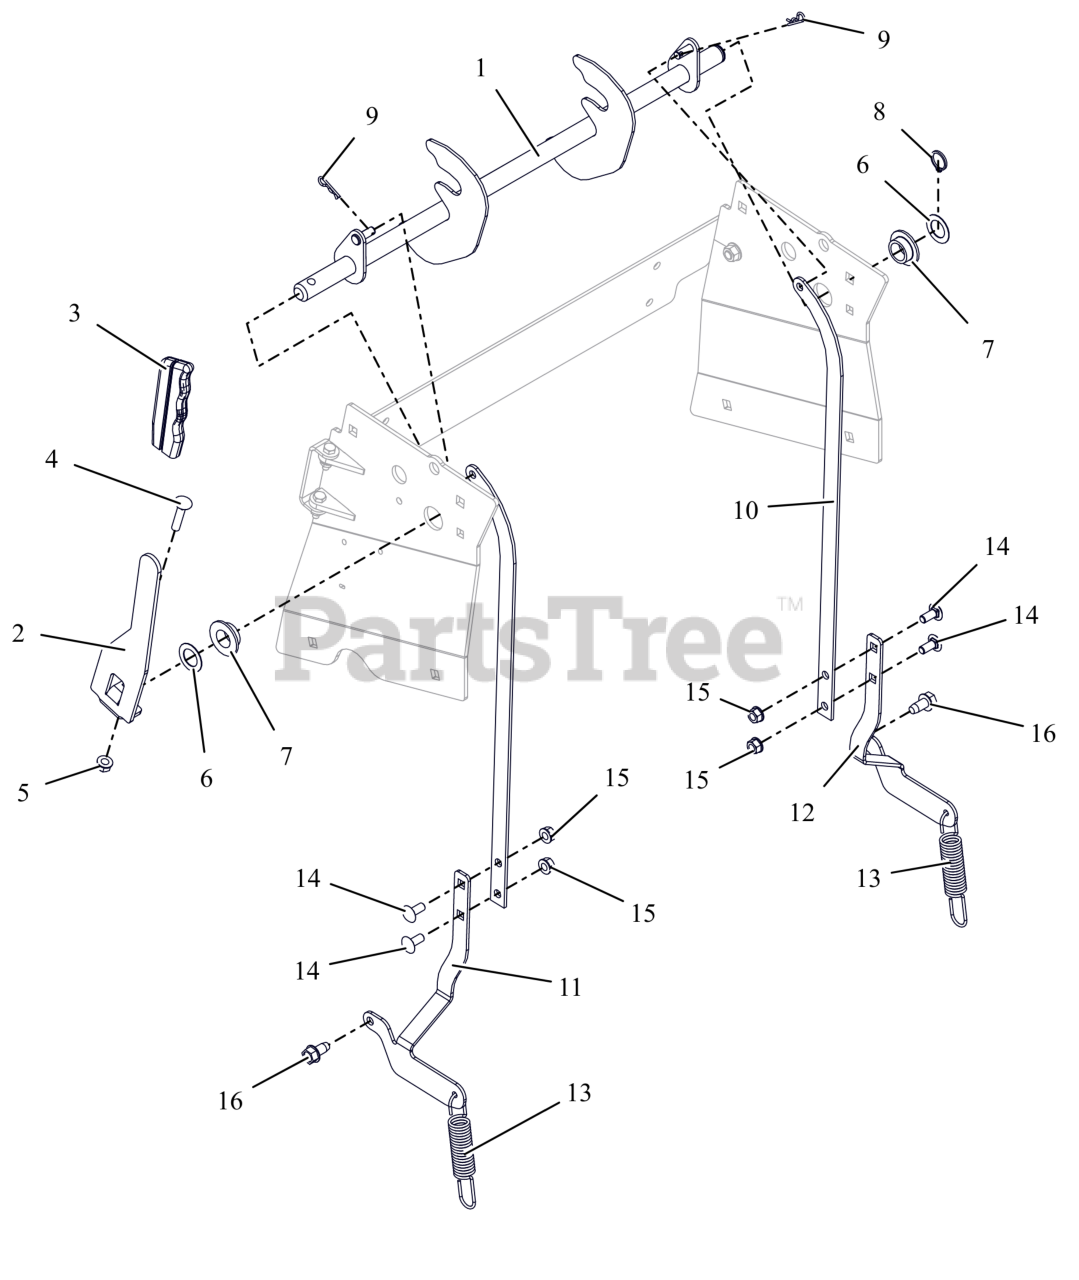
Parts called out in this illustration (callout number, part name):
1	WLDMT-48-52"PARK BRK SHFT(BLK)
2	HANDLE, PARK BRAKE (BLACK)
3	GRIP, PARKING
4	BLT,RHSN .31-18X1.50 G5 ZCC
5	NUT,LK-CTR-FLG .31-18 GF ZCC
6	WSHR-FL-STL 0.76X1.225X0.032 ZCC
7	BSHG-FLG .762X1.48X.44 NYL
8	RG-RTNG-EXT .689X.078
9	PIN, HAIR #213 .08X1.19 ZCC
10	LINKAGE- PARK BRAKE
11	LINKAGE-PARK BRK LOWER RH(BLK)
12	LINKAGE-PARK BRK LOWER LH(BLK)
13	SG-TENS .105X.85X5.00 WLD 40
14	BLT, RHSSN.31-18X.750 G5 ZCC
15	NUT,LK-CTR-FLG .31-18 GF ZCC
16	SCR,TAP .375-16X.75 HWH TR ZCC
